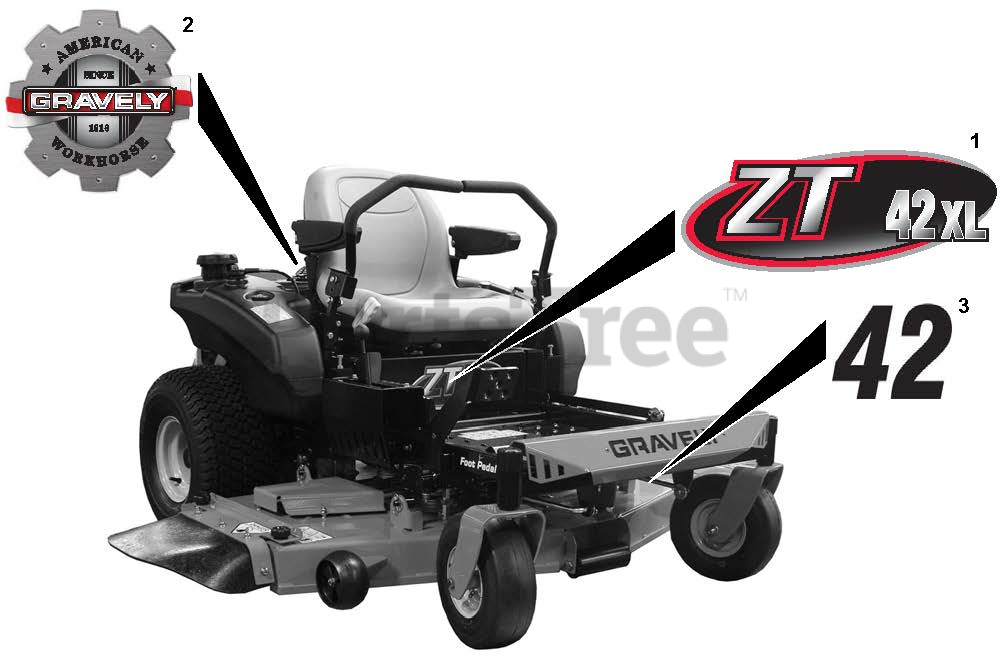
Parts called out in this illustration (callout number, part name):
1	Decal, 42 ZT XL
1	Decal, 48 ZT XL
1	Decal, 54 ZT XL
2	Decal, Gravely American Heritage
3	Decal, 42"
3	Decal, 48"
3	Decal, 54"
